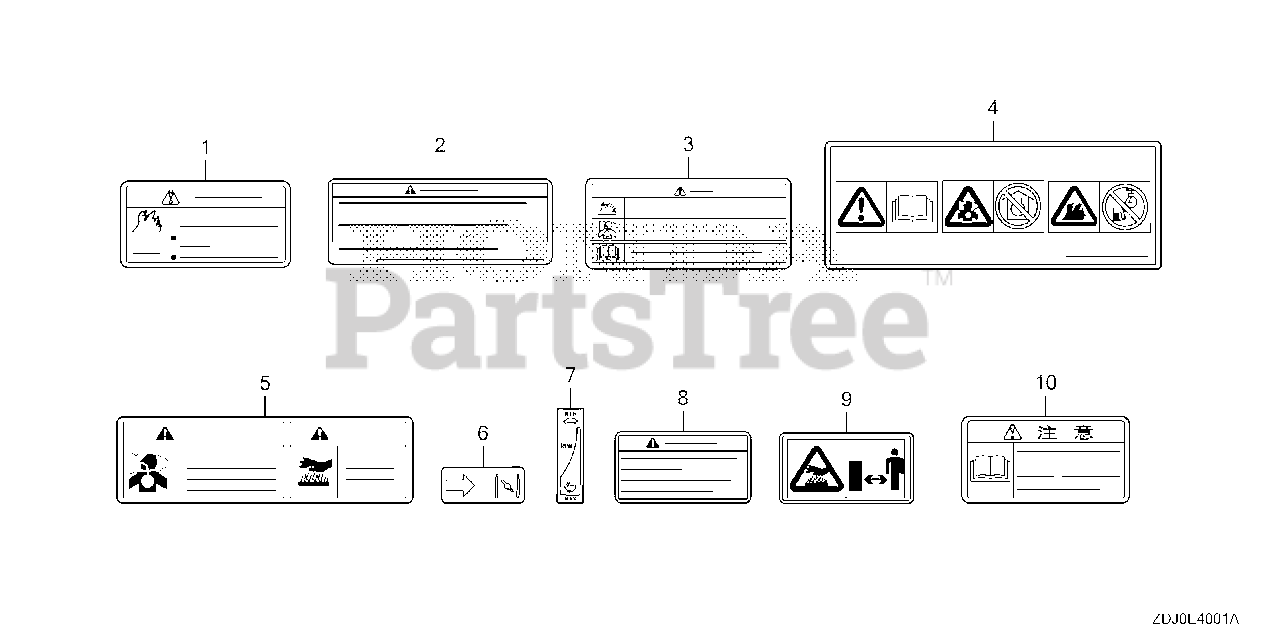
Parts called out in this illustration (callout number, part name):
2	MARK, OPERATOR CAUTION (ENGLISH)
2	MARK, OPERATOR CAUTION (FRENCH)
8	MARK, EX. CAUTION (ENGLISH)
8	MARK, EX. CAUTION (FRENCH)
